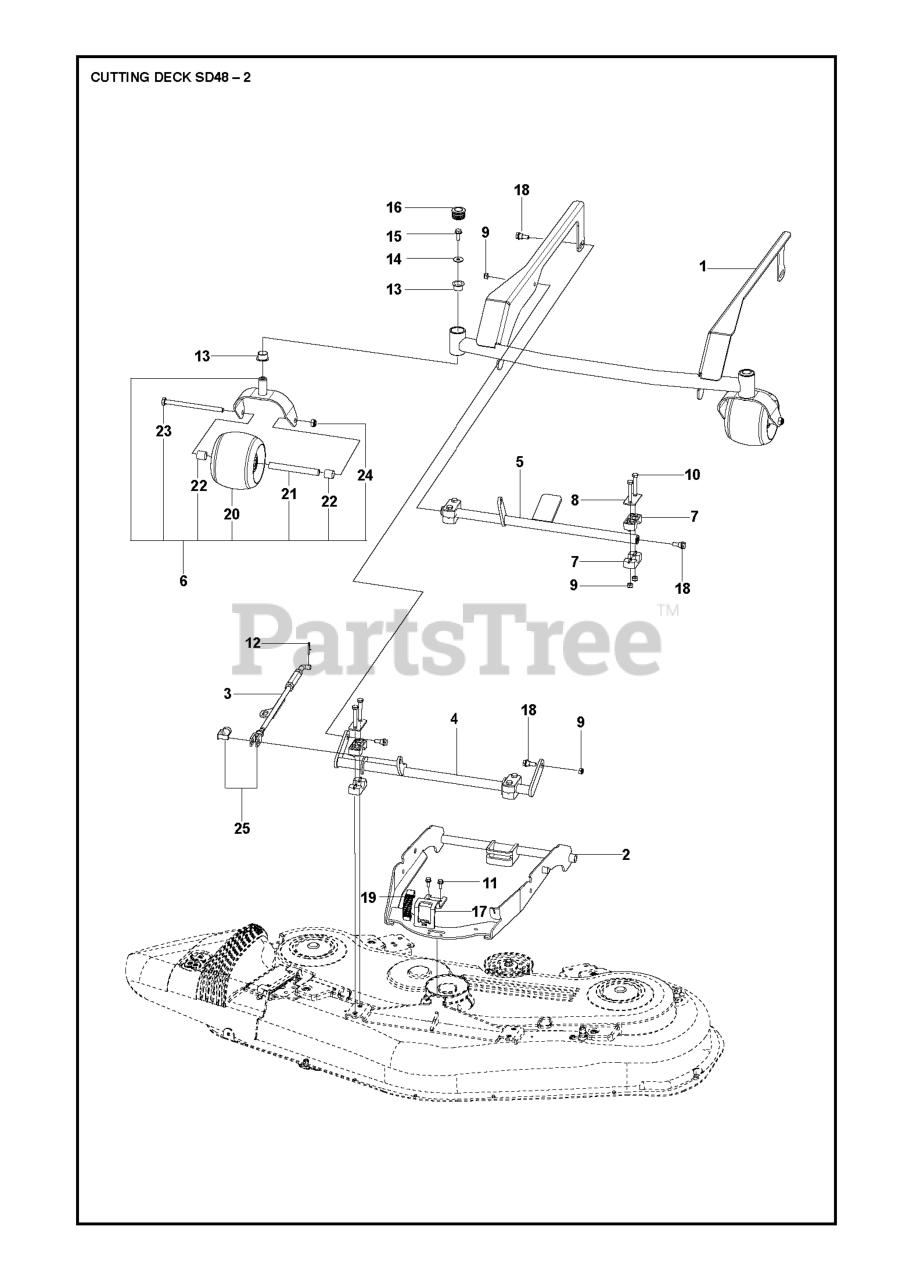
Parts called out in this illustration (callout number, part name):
2	DECK ATTACHMENT
3	ROD.PARALLEL
6	PIVOT WHEEL ASSY
9	LOCKNUT M8
11	SCREW
13	BUSHING FLANGE.79
19	CLIP GRAY
20	DECK ROLLER, FRONT
24	NUT
